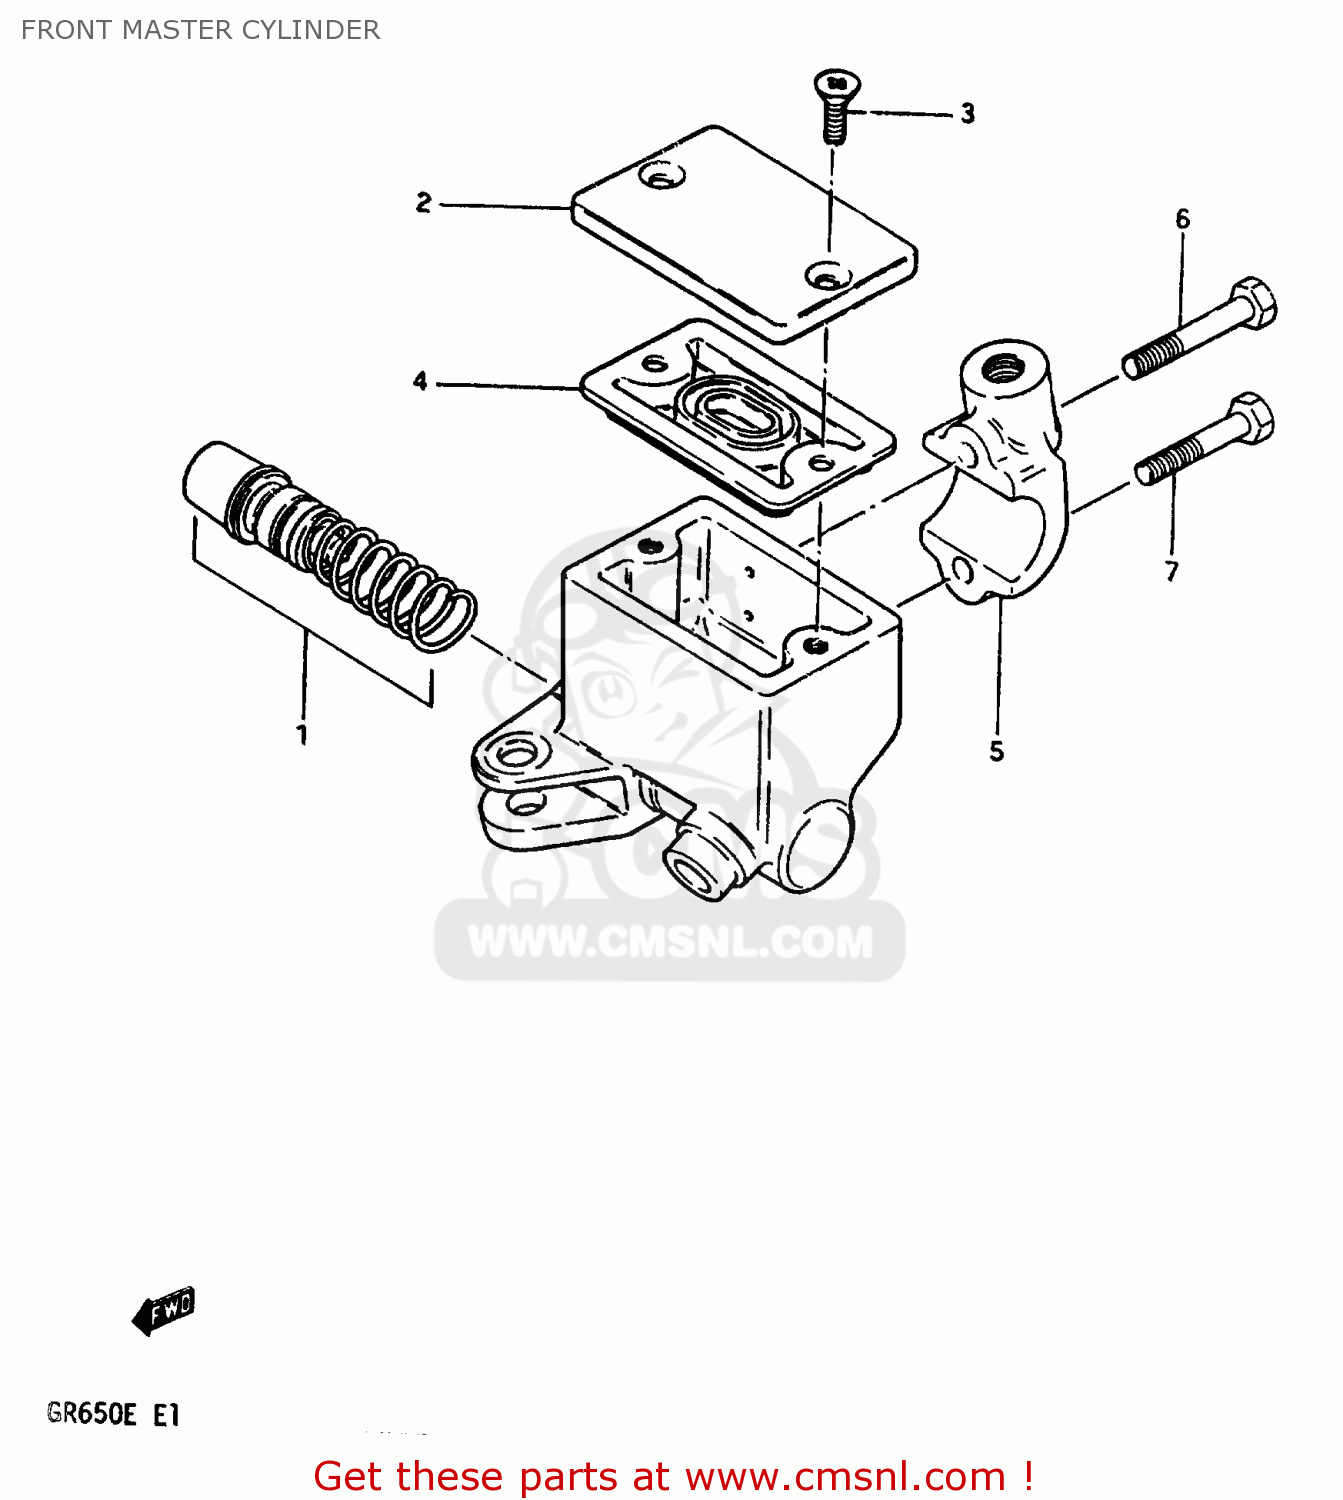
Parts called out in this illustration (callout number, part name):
1	PISTON & CUP SET
2	CAP
3	SCREW,RESERVOIR CAP
4	DIAPHRAGM,MASTER CYLINDER
5	HOLDER
6	BOLT,MASTER CYLINDER H
7	BOLT,MASTER CYLINDER H
